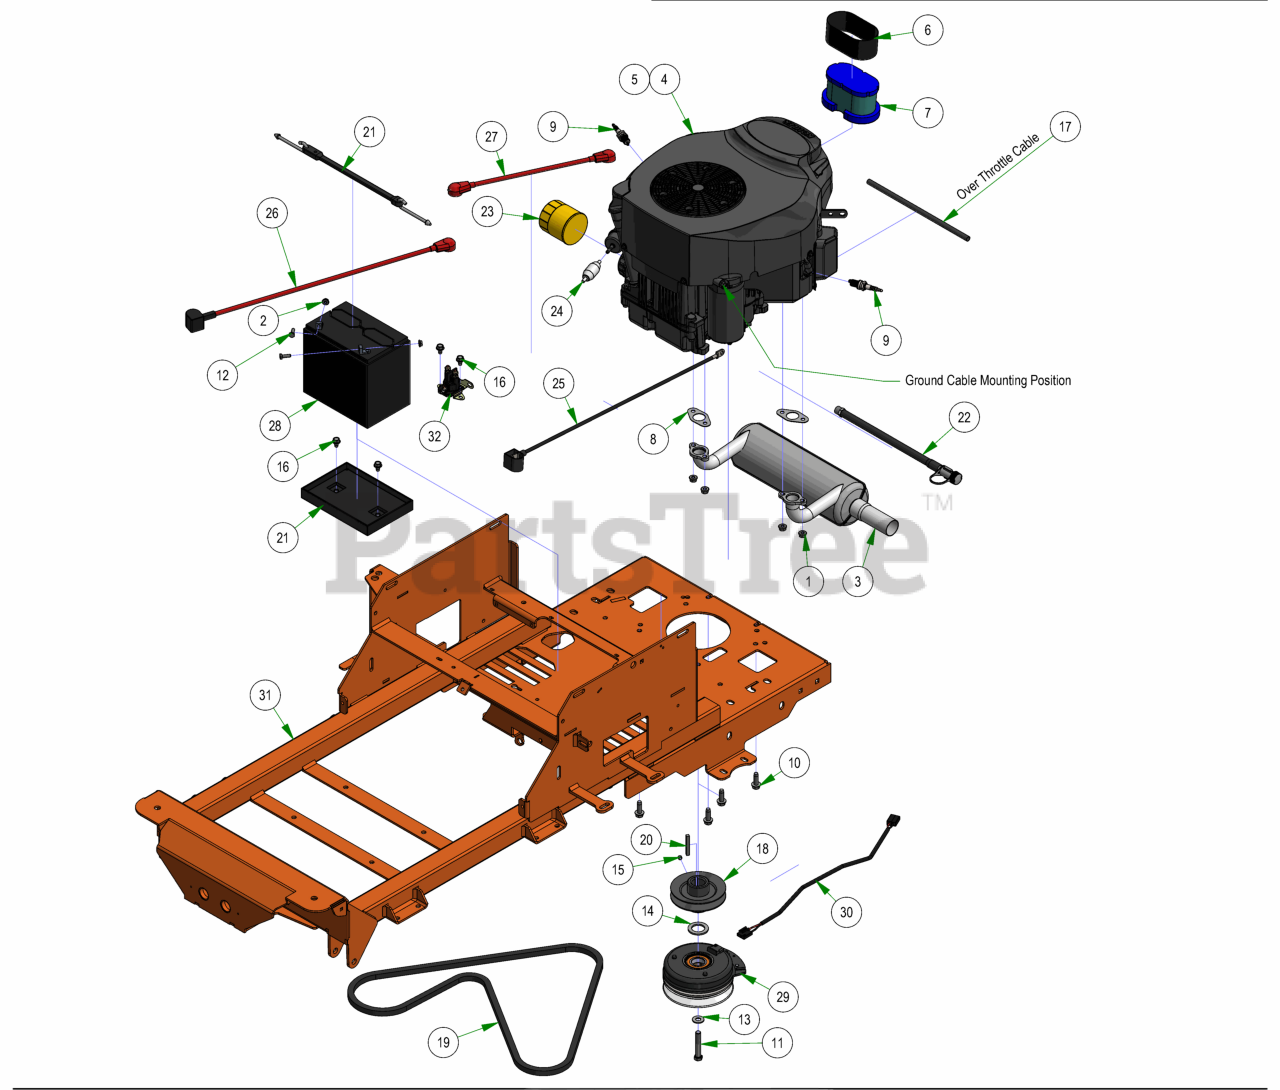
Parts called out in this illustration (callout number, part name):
1	M8 Nut Connects the 015-1012-00 and the 015-8240-00
2	1/4-20 HEX SERRATED FLANGE NUT HARD/ZINC
3	Kohler Muffler
4	New KT745 Kohler Engine
5	KT726-3004 Kohler Engine 1 1/8" Shaft
6	Air Pre-Cleaner for 015-2026-00
7	Air Filter Element for 015-2026-00
8	Exhaust Gasket
9	Spark Plug
10	3/8-16 X 1-1/8 HEX WASHER UNSLOT SERRATED (TRI-LOB) TRS ZINC YELLOW
11	7/16-20 X 2.5" HEX Bolt GR.8 W/Patch
12	1/4-20 X 3/4 HEX CAP SCREW (GR.5) ZINC
13	3/8 FLAT WASHER USS (1" OD) ZINC
14	1.140 ID X 1.750 OD X .132 THICK FLAT WASHER PLAIN
15	5/16-24 X 1/4 SOCKET SET SCREW (CUP PT) PLAIN
16	5/16-18 X 1/2 HWH unslot (F) tcs zinc
17	Braided Heat Shielding, 12"
18	4 3/4 Motor Pulley
20	1/4 X 2 SQ MACHINERY KEY 1018 STL PLAIN
21	2023 Battery Hold Down Assembly
22	Kohler Oil Drain
23	25 HP Kohler Oil Filter ZT?MZ
24	Universal Inline Fuel Filter
25	24 inch Black Cable – MZ/ZT
26	24" Red Battery Cable
27	14" Red Battery Cable
28	SP-35 Battery
29	120 Ft Lb. Clutch - 1 1/8" Shaft
30	Clutch Pigtail
31	2025 ZT Elite Frame
